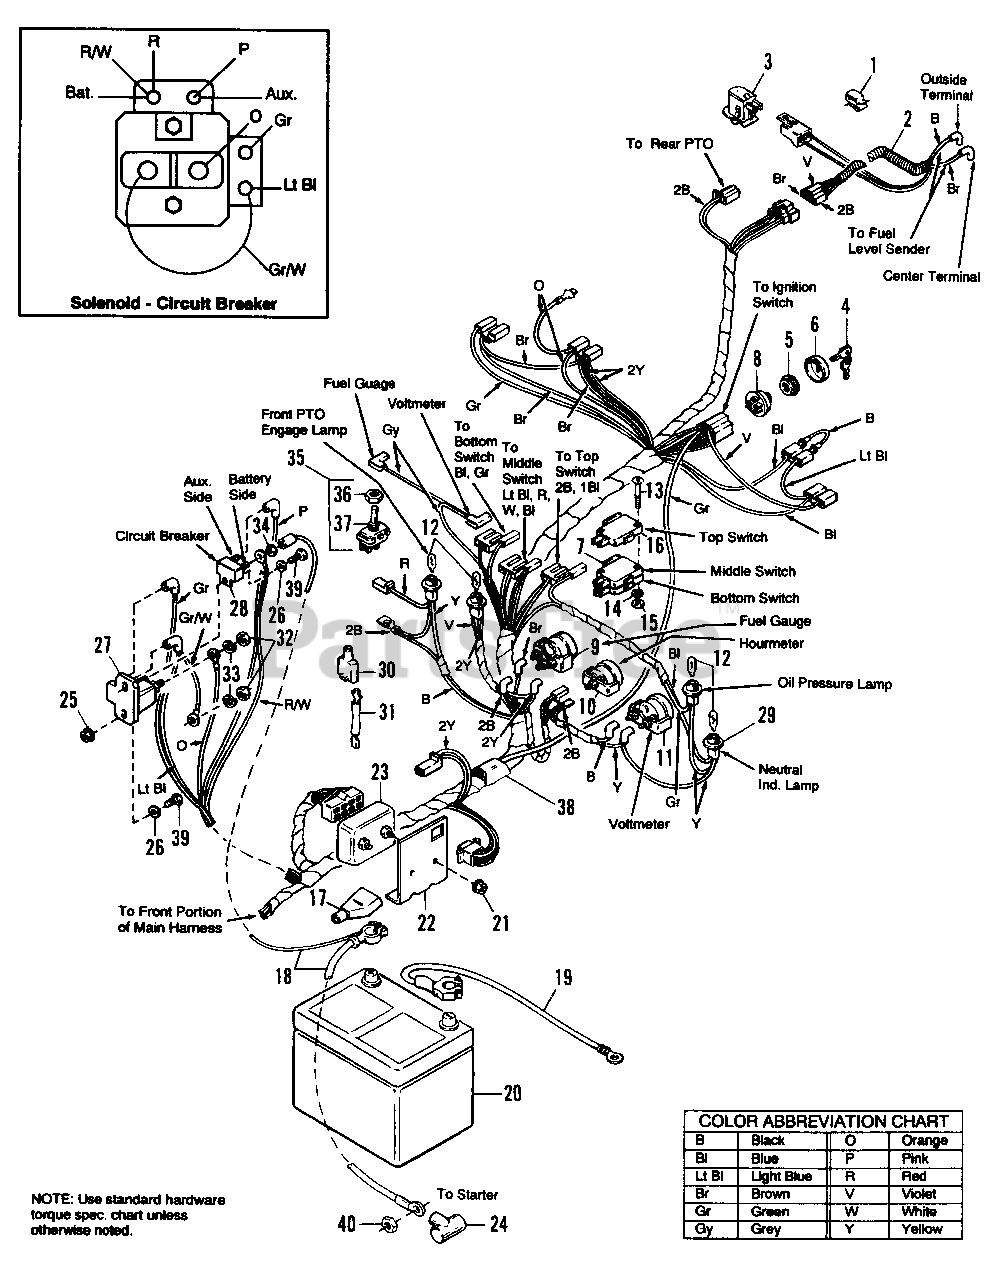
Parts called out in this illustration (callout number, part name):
1	CLIP, Tinnerman
2	HARNESS, Rear
3	SAFETY SWITCH (Seat), Operator Present
5	NUT, Adaptor
6	COVER, Ignition
7	DUAL INTERLOCK SWITCH
8	SWITCH
9	GAUGE, Fuel
13	SCREW, R.H., #5-24 x 1-1/2
14	LOCKWASHER, #5
15	NUT, Hex, #5-40
16	SWITCH, Interlock (Under Dash) Shift Lever
17	PROTECTOR, Battery (Red)
18	CABLE (Battery to Solenoid)
19	CABLE (Battery to Ground)
20	BATTERY (491 AMP Cold Crank Rating)
21	NUT, w/Washer, #8-32
22	BRACKET, Interlock, Mod.
23	INTERLOCK MODULE
24	COVER, Terminal
25	NUT, Hex, Flange, Whizlock, 1/4-20
26	WASHER, Plain, 1/4
27	SOLENOID (12 Volt DC)
28	BREAKER, Circuit
29	BULB HOLDER
30	CONNECTOR, 3 Way
31	WIRE ASSY., Diode
32	NUT, Hex, Jam, 5/16-24 Zinc Pltd.
33	LOCKWASHER, 5/16, Zinc Pltd.
34	NUT, Hex & Washer, #10-32
35	SWITCH ASSY., PTO (incl. Ref. Nos. 36 & 37)
36	NUT, Special
38	WIRING HARNESS (Main)
39	CAPSCREW, Hex Hd. 1/4-20 x 3/4
40	NUT, Hex Flange, M8-125
